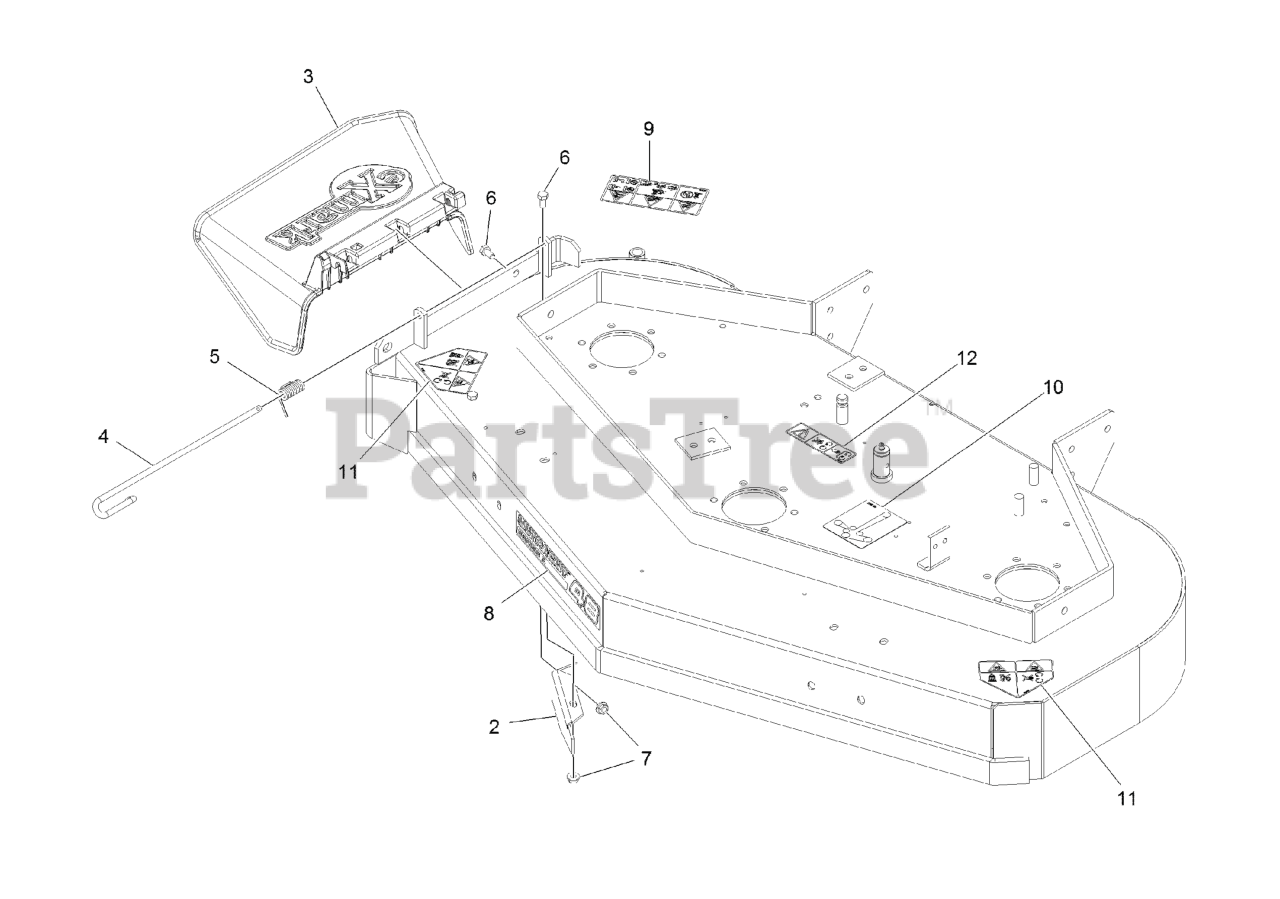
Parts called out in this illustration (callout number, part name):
2	BAFFLE-DOGLEG
3	CHUTE DEFLECTOR XRK M056
4	PIN-CHUTE
5	SPRING, TORSION
6	SCREW-HH
8	DECAL-ULTRACUT 48 SERIES 3
9	DECAL-WARNING THROWN OBJ
10	DECAL-ROUTING, BELT
11	DECAL-DANGER
12	DECAL-COVER, MISSING
